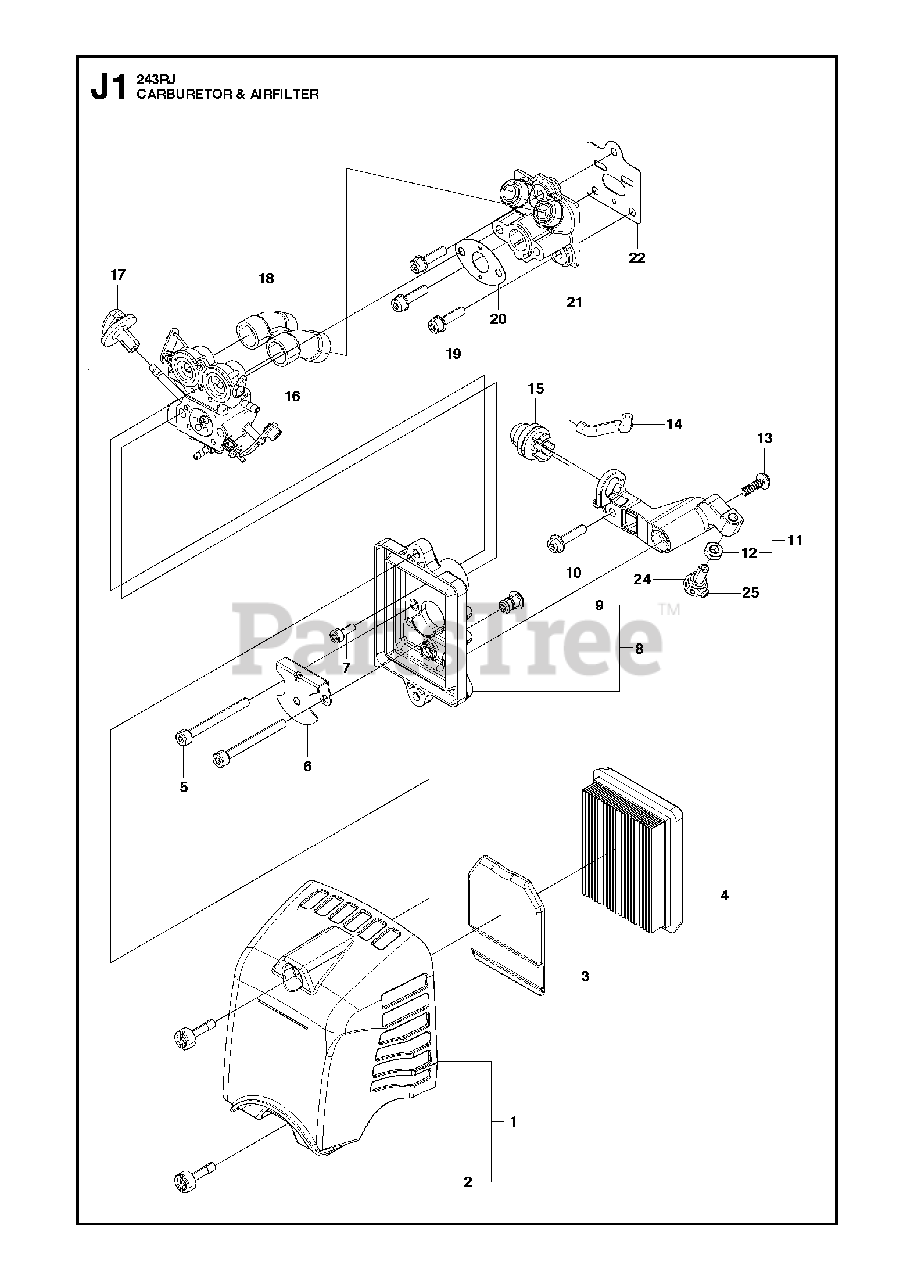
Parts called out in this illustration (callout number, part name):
2	SCREW
7	BOLT M4 X 12 T27
9	GROMMET
11	BRACKET ASSY
12	NUT
15	PRIMARY BTN
19	BOLT, TORX
24	SCREW CABLE ADJUST
